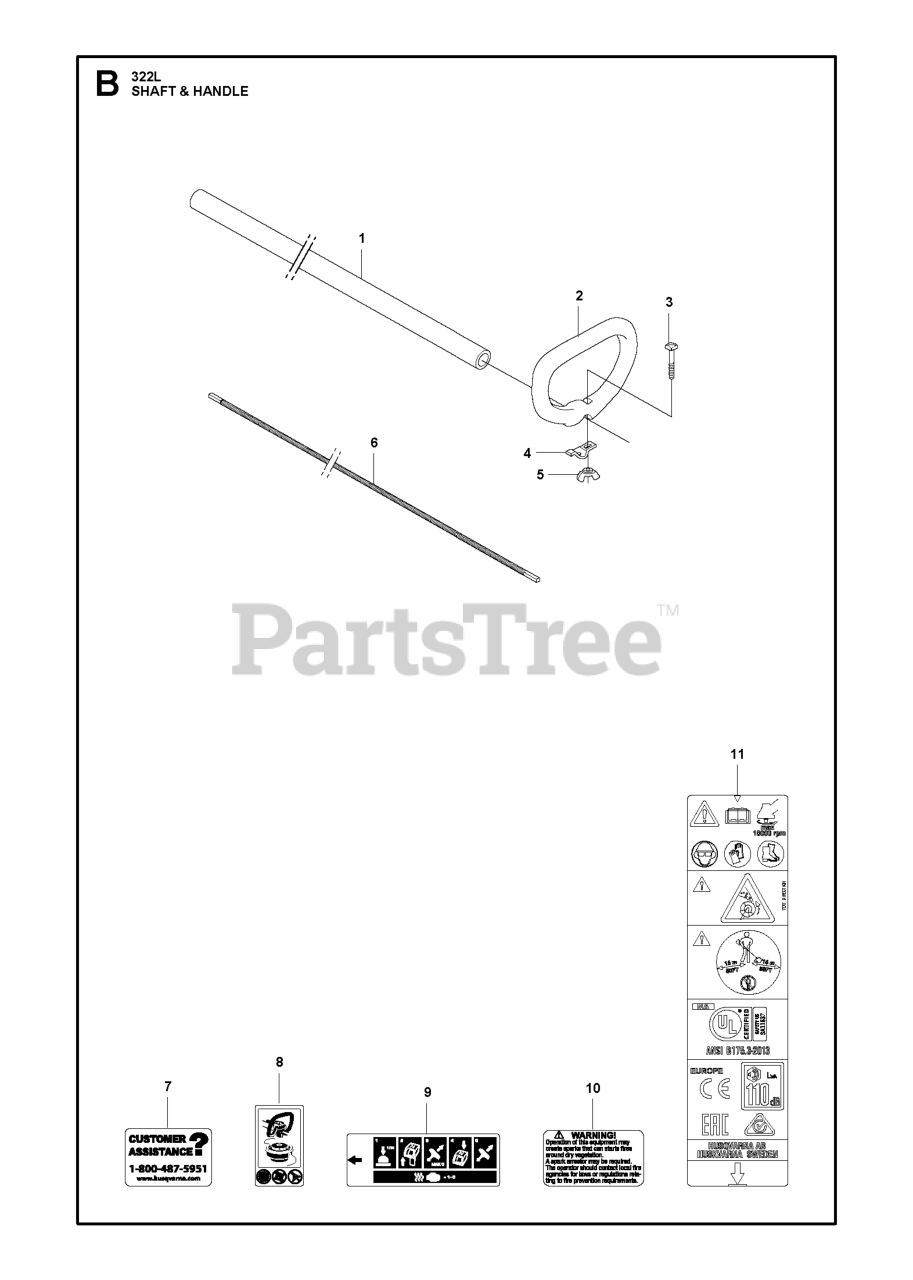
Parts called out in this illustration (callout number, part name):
1	TUBE COMPLETE
2	HANDLE, LOOP
4	HOLDER
6	FLEX DRIVE SHAFT
8	DECAL WARNING "NO BLADES"
9	DECAL START REMINDER 523/525
10	DECAL SPARK ARRESTOR WARNING
11	DECAL WARNING
